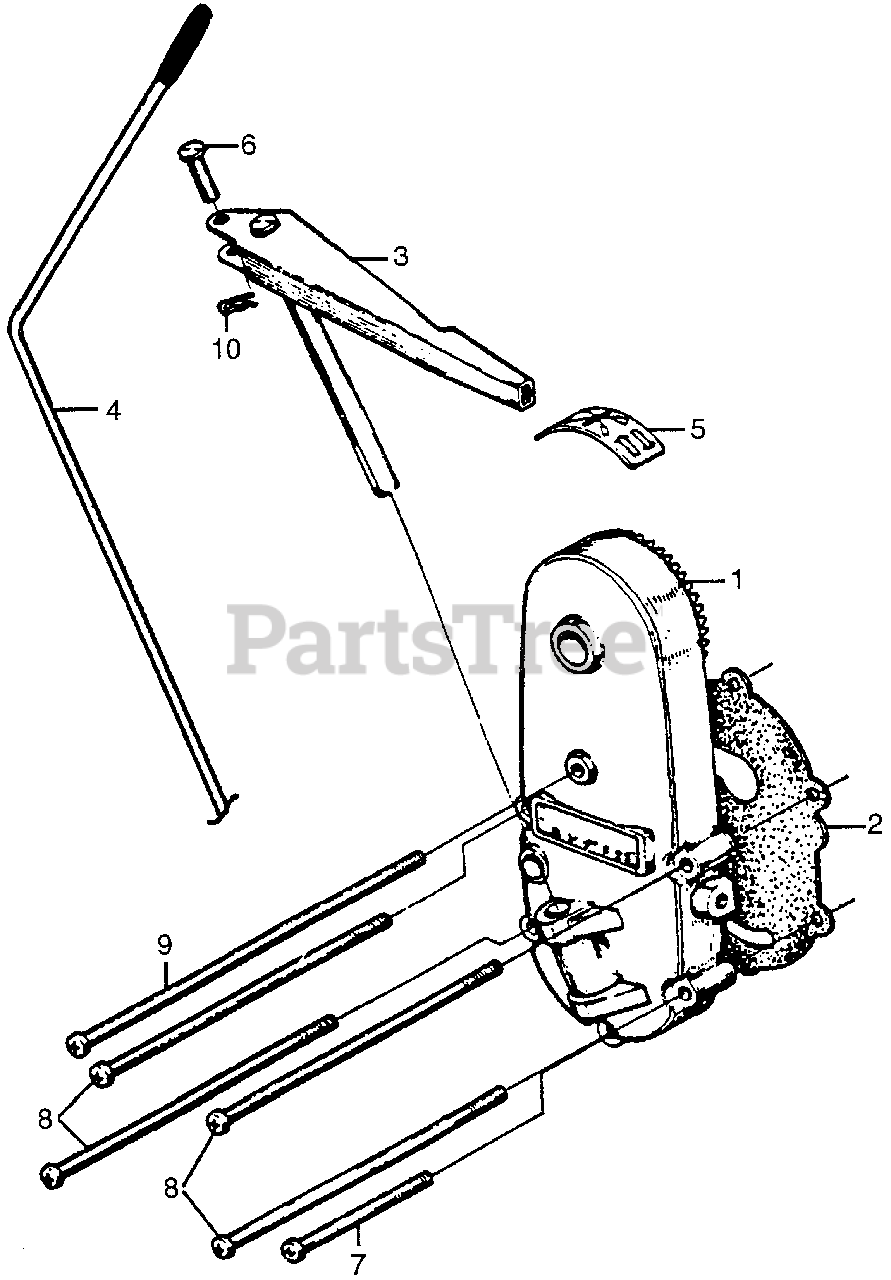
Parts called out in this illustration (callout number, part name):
1	COVER, L. SIDE (NOT AVAILABLE)
2	GASKET, L. SIDE
4	LEVER, CHANGE
5	MARK, CHANGE LEVER (NOT AVAILABLE)
6	PIN (4X19)
7	SCREW, PAN (6X40)
8	SCREW, PAN (6X90) (SOURCE: VINTAGE PARTS INC.)
9	SCREW, PAN (6X112) (NOT AVAILABLE)
10	PIN, LOCK (4MM)
